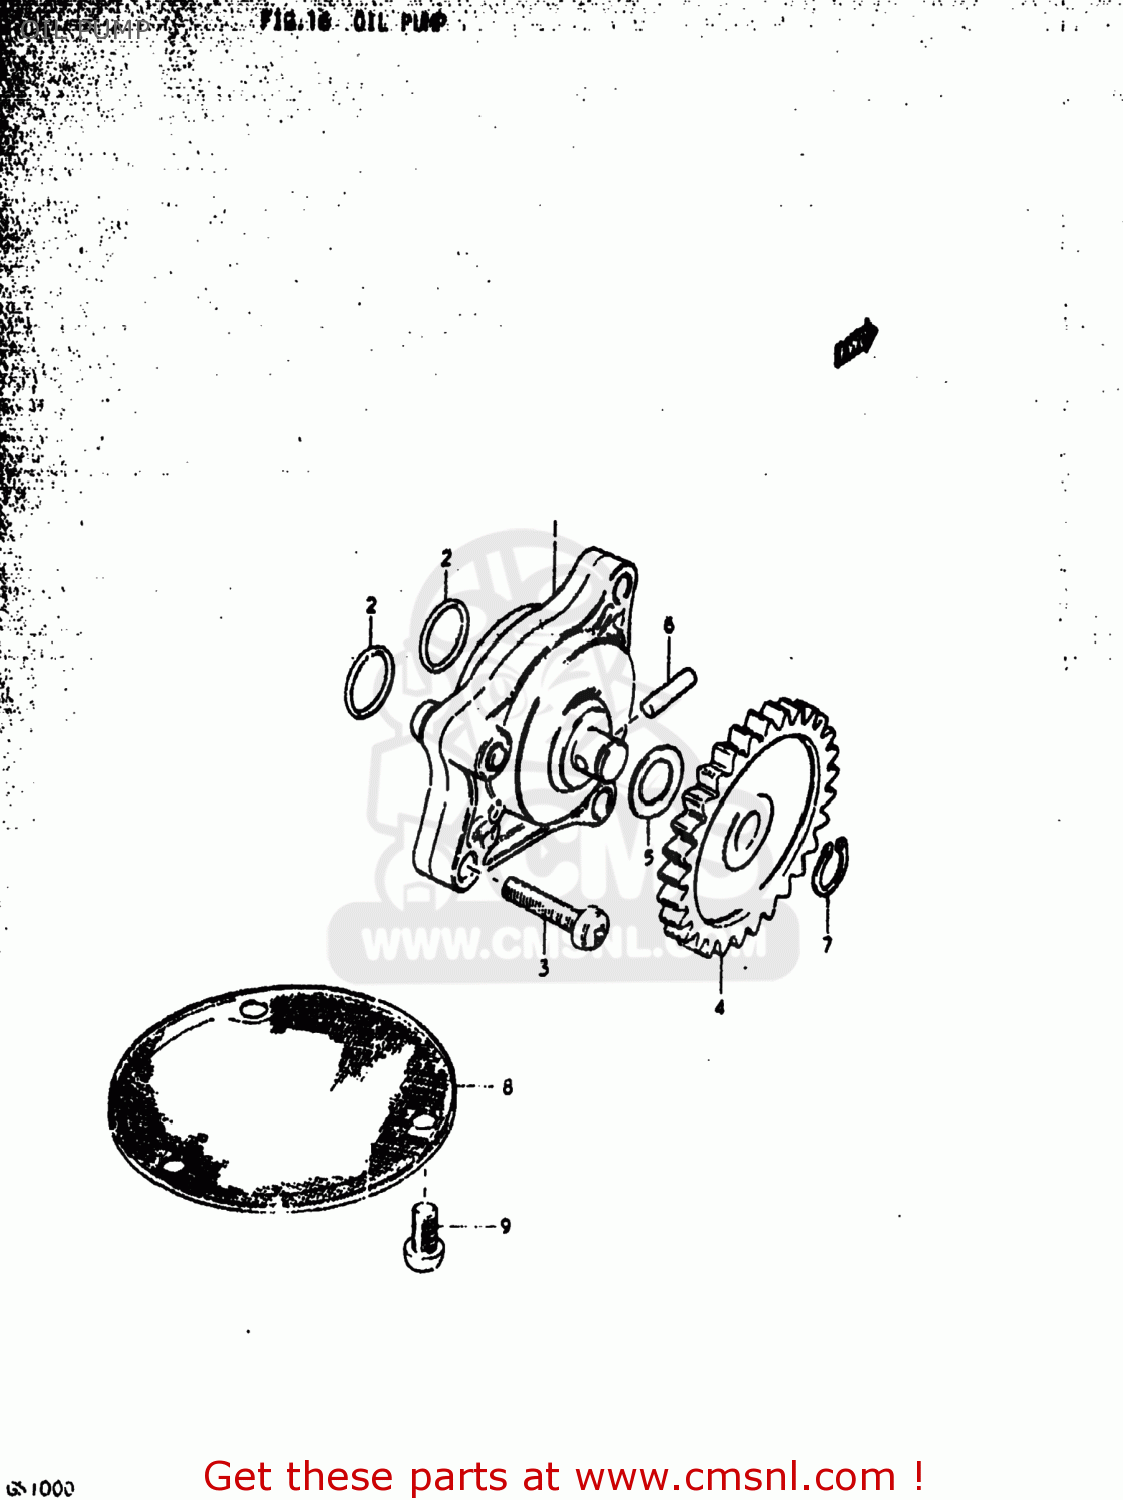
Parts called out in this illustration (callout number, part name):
1	PUMP ASSEMBLY,OIL
2	O RING(D:1.9,ID:13)
3	SCREW
4	GEAR,OIL PUMP DRIVEN
5	SHIM
6	PIN(4X15.8)
7	CIRCLIP
8	STRAINER,ENGINE OIL
9	SCREW 6X12
